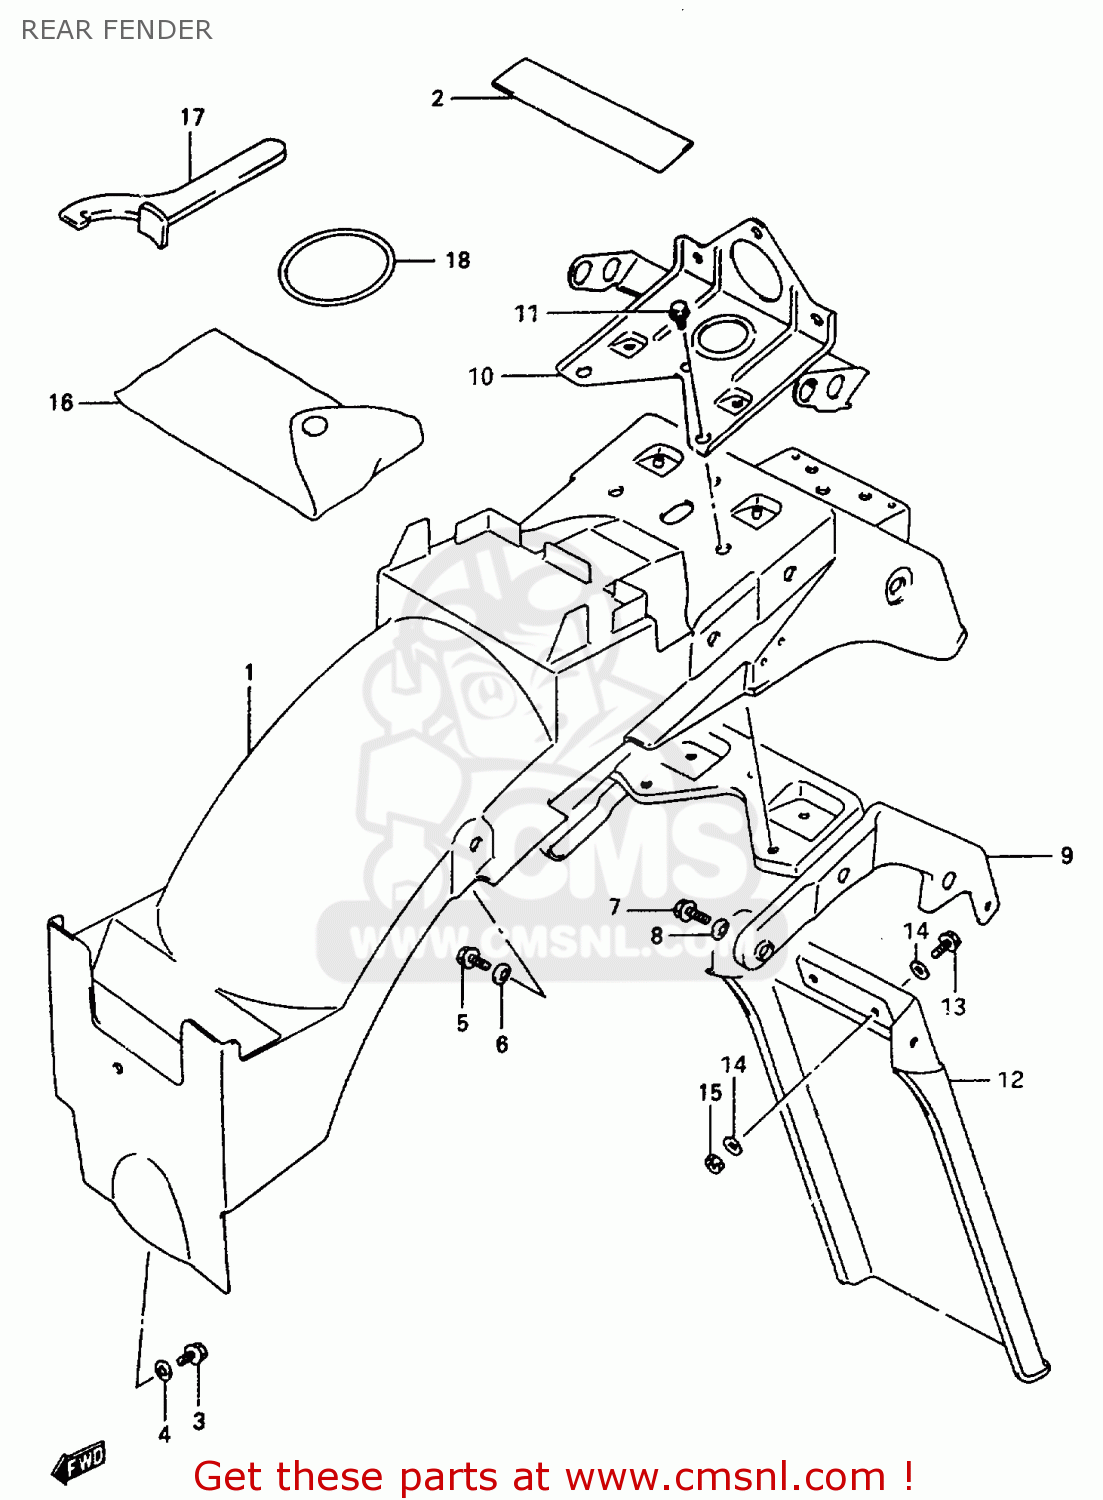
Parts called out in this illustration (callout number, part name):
1	BODY,RR FENDER
2	CUSHION,RR FENDER
3	BOLT
4	WASHER
5	BOLT
6	WASHER
7	BOLT
8	WASHER
9	REINF,RR FENDER
10	BRACKET,RR LAMP
11	BOLT
12	EXTENSION, REAR FENDER
13	SCREW
14	WASHER(6.5X16X1.2)
15	NUT
16	TOOL ASSY
17	CLAMP
18	O RING(D:3.5,ID:61)
